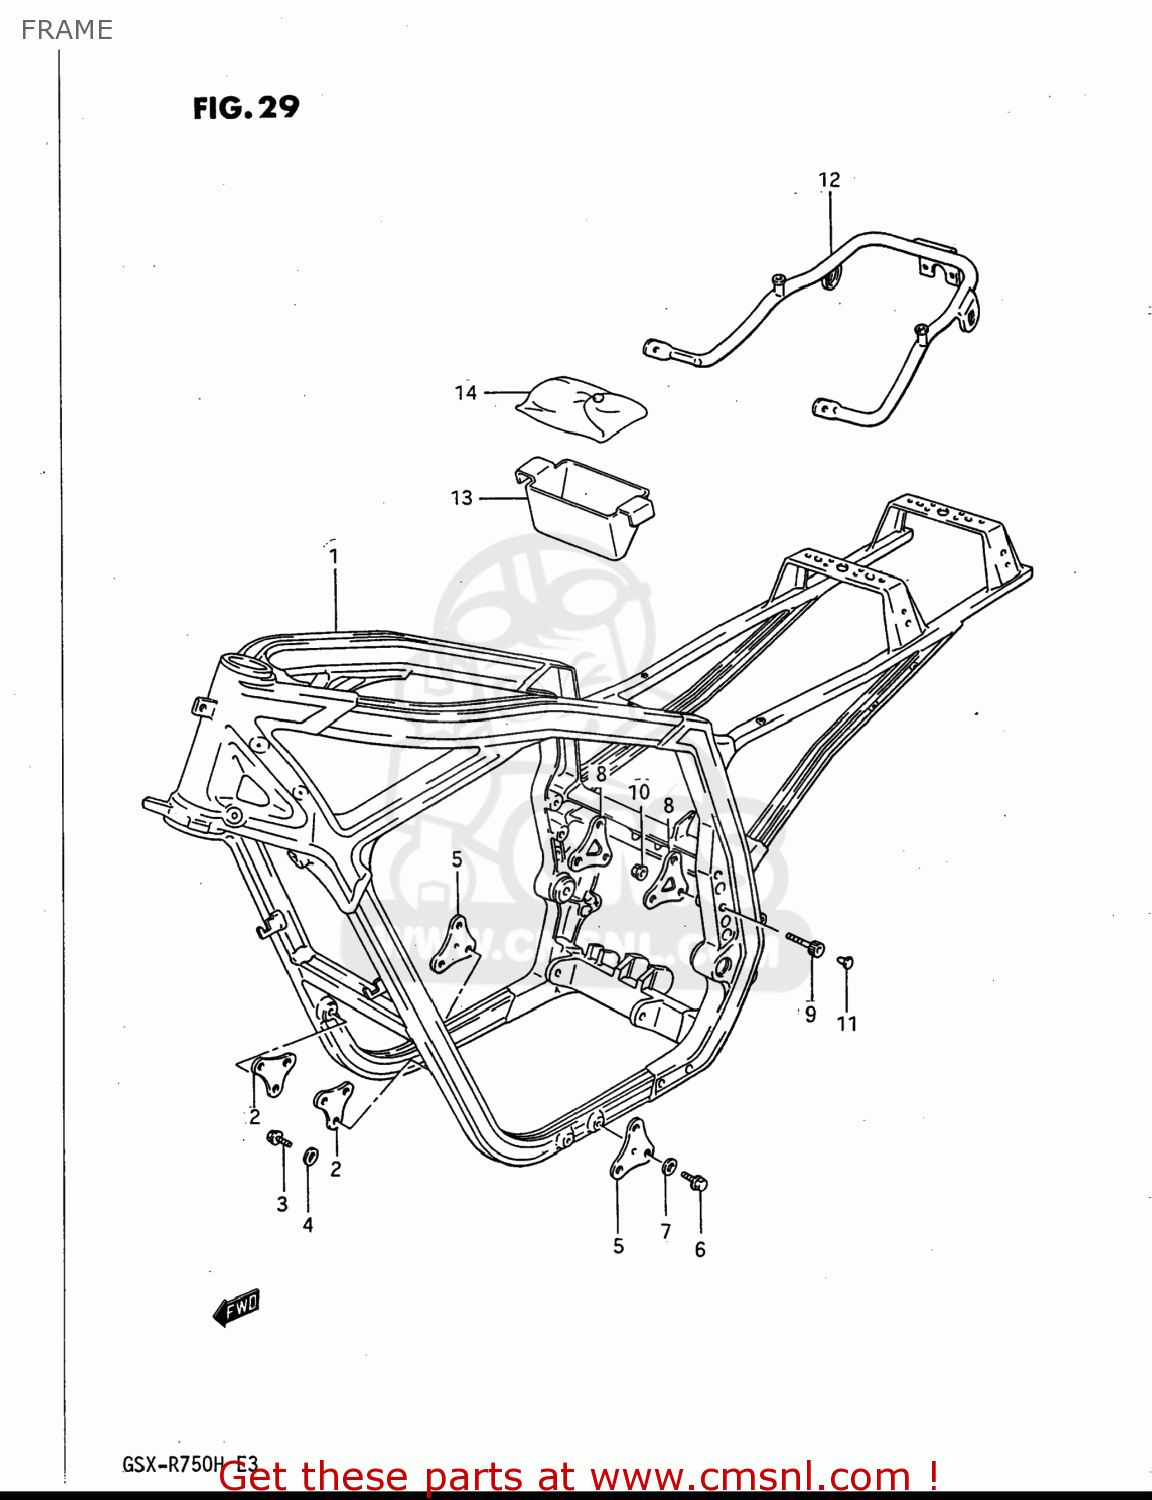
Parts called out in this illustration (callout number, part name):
1	FRAME
2	PLATE,ENGINE MOUNTING NO
3	BOLT
4	WASHER (8.2X20X1.6)
5	PLATE,ENGINE MOUNTING NO.1
6	BOLT
7	WASHER (8.2X20X1.6)
8	PLATE,ENGINE MOUNTING NO
9	BOLT, RH
10	NUT
11	CAP,ENGINE MOUNTING
12	GRIP COMP,REAR
13	HOLDER,TOOL
14	TOOL ASSY
